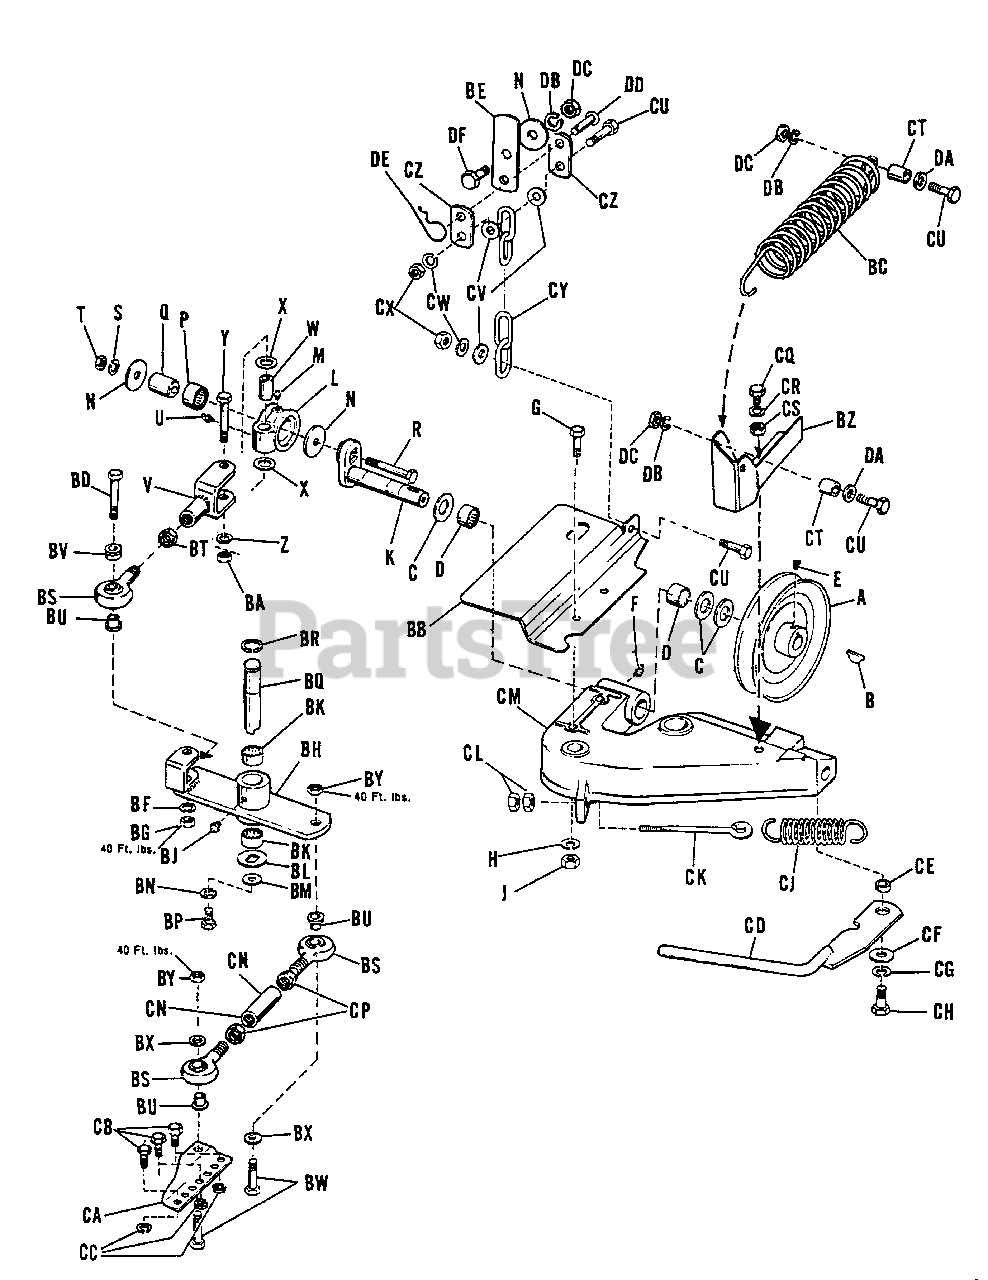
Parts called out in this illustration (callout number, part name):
A	Drive Pulley
B	Key, Hi-Pro
D	Bearing, Needle
E	Set Screw Sq. Hd. 5/16"-18 NC x 1/2" lg.
F	Fitting, Grease
G	Capscrew, Hex Hd., 3/8"-16 NC x 1" lg.
H	Lockwasher, 3/8"
J	Nut, Hex, Full, 3/8"-16 NC
K	Shaft, Crank
L	Housing, Pitman Bearing
M	Fitting, Grease
N	Washer
P	Bearing, Needle
Q	Race, Inner, Pitman Bearing
R	Capscrew, Hex Hd., 3/8"-16 NC x 2-1/4" lg.
S	Lockwasher, 3/8"
T	Nut, Hex, Full, 3/8"-16 NC
U	Fitting, Grease, 90 Degree
V	Clevis Assembly, Pitman
W	Bearing, Pivot Block
Y	Capscrew, Hex Hd., 3/8"-16 NC x 2-1/4" lg.
Z	Lockwasher, 3/8"
BA	Nut, Hex, Full, 3/8"-16 NC
BD	Capscrew, Hex Hd., 3/8"-16 NC x 2-1/2" lg.
BE	Chain Support
BF	Lockwasher, 3/8"
BG	Nut, Hex, Full, 3/8"-16 NC
BH	Rocker Arm Assembly
BJ	Fitting, Grease
BK	Bearing, Needle
BM	Washer, Plain, 3/8"
BN	Lockwasher, 3/8"
BP	Capscrew, Hex Hd., 3/8"-16 NC x 3/4" lg.
BQ	Shaft, Rocker Arm
BR	Ring, Retaining
BT	Nut, Hex, Full, 1/2"-20 NF
BW	Bolt, Hex Hd.,
BY	Nut, Hex, Full, Lock, 3/8"-24 NF
BZ	Mounting Assy. Cable
CA	Head, Sickle
CB	Capscrew, Hex Hd., 5/16"-24 NF x 5/8" lg.
CC	Washer, Lock, 5/16"
CD	Latch Assembly
CE	Spacer, Latch
CF	Washer, Plain
CG	Lockwasher, 7/16"
CH	Capscrew, Hex Hd., 7/16"-14 NC x 1-1/4" lg.
CL	Nut, Hex, Full, 5/16"-18 NC
CN	Pivot End Rod
CP	Nut Hex Jarn 1/2"-20 NF
CQ	Capscrew, Hex Hd., 7/16"-14 NC x 1" lg.
CR	Washer Lock 7/16"
CS	Nut, Hex Full
CU	Capscrew, Hex Hd., 3/8"-16 NC x 1" lg.
CV	Washer, Plain, 3/8"
CW	Lockwasher, 3/8"
CX	Nut, Hex, Full, 3/8"-16 NC
CY	Chain, Lift
CZ	Link, Mower Lift
DA	Washer Plain 3/8"
DB	Washer Dock 3/8"
DC	Hex, Nut, Full 3/8"-16 NC
DE	Clip, Spring
DF	Capscrew, Hex Hd., 3/8"-16 NC x 1" lg.
